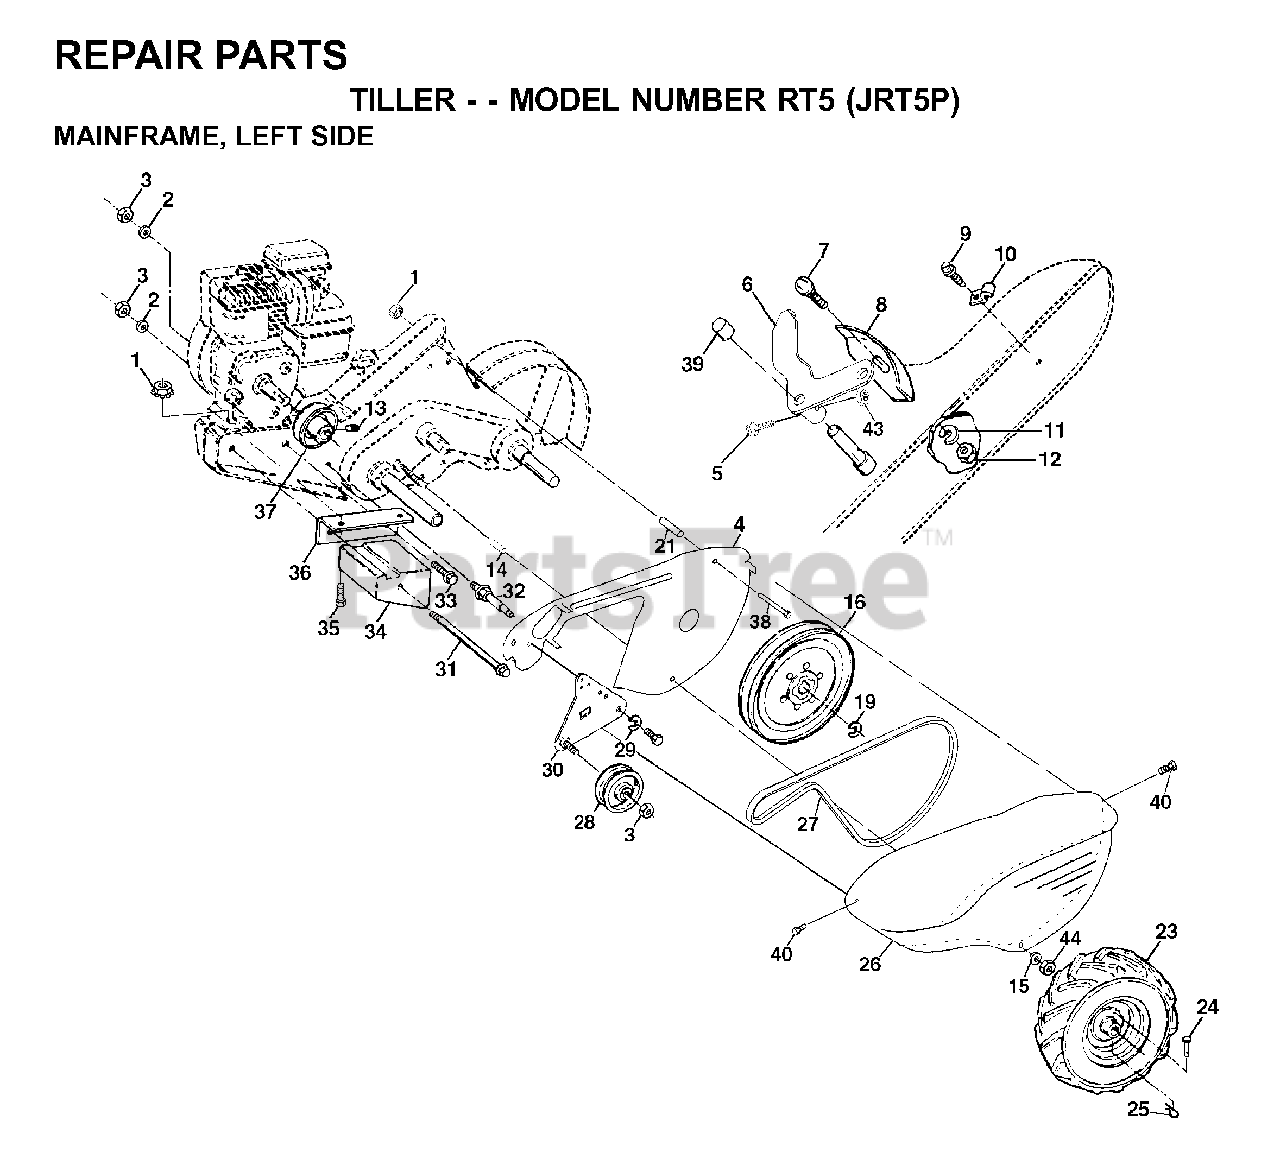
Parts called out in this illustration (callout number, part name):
1	NUT
2	WASHER, LOCK 3/8
3	NUT.HEX.3/8-16UNC
5	SCREW, SHIFT LEVER
6	LEVER ASM CRT
9	SCREW.HEX.WSH.SLT.#10-24X.50
10	CONDUIT CLIP T
11	LOCKWASHER
12	NUT
13	SET SCREW **
14	SPACER-SPLIT.327 X .42
15	WASHER
16	SHEAVE, TRANSMISSION
19	RETAINING RING LT
21	SPACER CRT
24	RIVET,DRILLED
25	RETAINER M
27	V-BELT
28	PULLEY-IDLER TI
29	KLIP RING
30	BRACKET.ASM.IDLER
31	BOLT.FIN.HEX.3/8-16UNC
32	SHIFT ARM CRT
33	BOLT
34	COUNTERWEIGHT.LH.CRT
36	BRACKET LH CRT
37	ENGINE PULLEY
38	BOLT
39	CAP.PLUNGER.BLACK
44	LOCKNUT
532124366	RIM
532124718	VALVE STEM LT
